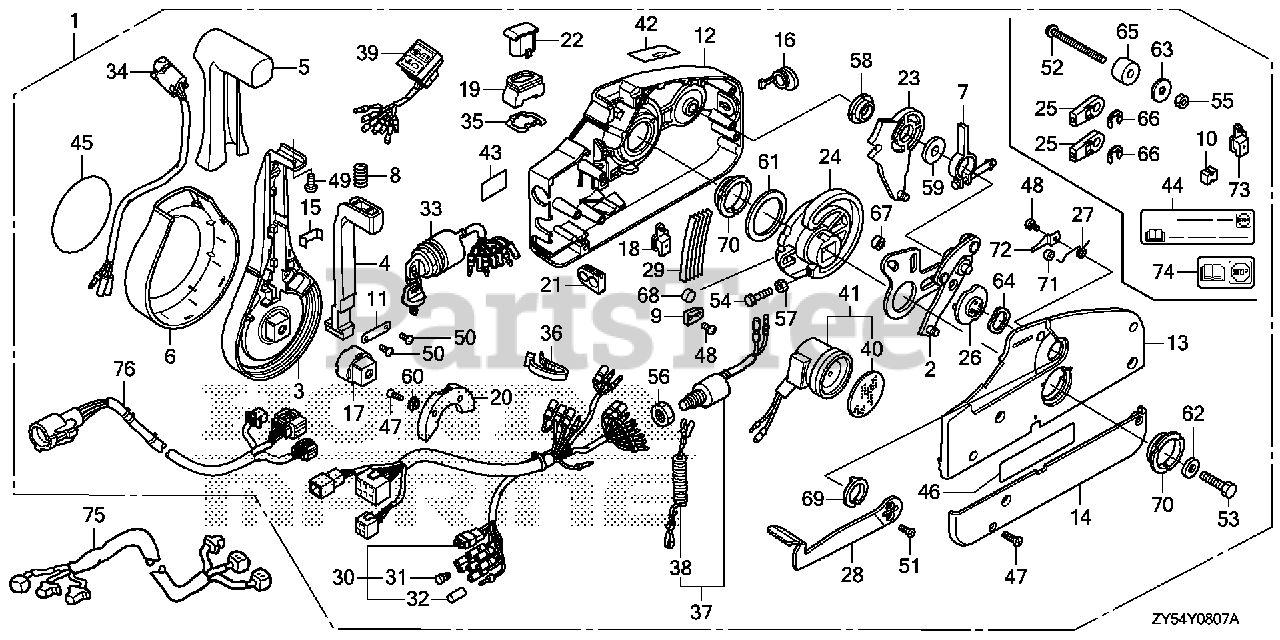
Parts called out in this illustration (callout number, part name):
1	BOX ASSY., REMOTE CONTROL (NHK MEC)
1	BOX ASSY., REMOTE CONTROL (TROLLING CONTROL)(NHK MEC)
2	PLATE ASSY.
3	LEVER, HAND
4	ARM, NEUTRAL LOCK
5	GRIP
6	COVER, LEVER
7	ARM ASSY., BRAKE
8	SPRING (2)
9	CLIP, DETENT
10	SPACER (1) (LOOSE PARTS)
11	BRACKET
12	HOUSING, FR.
13	HOUSING, RR.
14	PANEL, BACK
15	BRACKET, WIRE CLAMP
16	CAP, RUBBER
17	ADJUSTER
18	COVER, POWER TRIM-TILT WIRE (LOOSE PARTS)
19	SEAL, RUBBER
20	HOLDER, NEUTRAL LOCK
21	GROMMET, WIRE (14)
22	CAP, TROLLING CONTROL SWITCH BLANK
23	GEAR ASSY., SHIFT
24	GEAR, DRIVE
25	TERMINAL, CABLE (LOOSE PARTS)
26	DRUM ASSY., FREE THROTTLE
27	SPRING (1)
28	LEVER, FREE THROTTLE
29	SPRING, DETENT
30	CABLE ASSY., REMOTE CONTROL (B)
31	PLUG, CONNECTOR (INNER) (TROLLING CONTROL)
32	PLUG, CONNECTOR (OUTER) (ENGINE NO.)
33	SWITCH ASSY., COMBINATION (SINGLE) (DUAL)
34	SWITCH ASSY., POWER TRIM-TILT
35	PLATE, SWITCH
36	BAND, WIRE
37	SWITCH ASSY., EMERGENCY STOP
38	WIRE, EMERGENCY (SINGLE) (DUAL)
39	LAMP ASSY., INDICATION (2-LED)
39	LAMP ASSY., INDICATION
40	PLATE, TURN SIGNAL BUZZER DUAL QTY = (2) (SINGLE)
41	BUZZER, WARNING DUAL QTY = (2) (SINGLE)
42	MARK, FAST IDLE
43	MARK, EMERGENCY STOP (US) (LOOSE PARTS)
44	MARK, EMERGENCY STOP (US) (LOOSE PARTS)
45	MARK, EMBLEM
46	LABEL, SIGP
47	SCREW (5X18)
48	SCREW (4X6)
49	SCREW (5X10)
50	SCREW (4X10)
51	SCREW (5X12)
52	SCREW (6X90) (LOOSE PARTS)
53	BOLT (8X50)
54	BOLT (5X25)
55	NUT (6MM) (LOOSE PARTS)
56	NUT, HEX. (16MM) DUAL QTY = (2) (SINGLE)
57	NUT (5MM)
58	BEARING (1)
59	WASHER (3)
60	WASHER (4)
61	WASHER (5)
62	WASHER (8MM)
63	WASHER (7) (LOOSE PARTS)
64	WASHER, WAVE
65	SPACER (2) (LOOSE PARTS)
66	E-RING (6MM) (LOOSE PARTS)
67	ROLLER, DRIVE GEAR CAM
68	ROLLER
69	BEARING (2)
70	BEARING (3)
71	ROLLER, FREE THROTTLE
72	CLIP, ROLLER
73	COVER, POWER TRIM-TILT WIRE (LOOSE PARTS)
75	CABLE ASSY., REMOTE CONTROL EXTENSION Use from Frame SN 1300029.
76	CABLE ASSY., SWITCH PANEL
